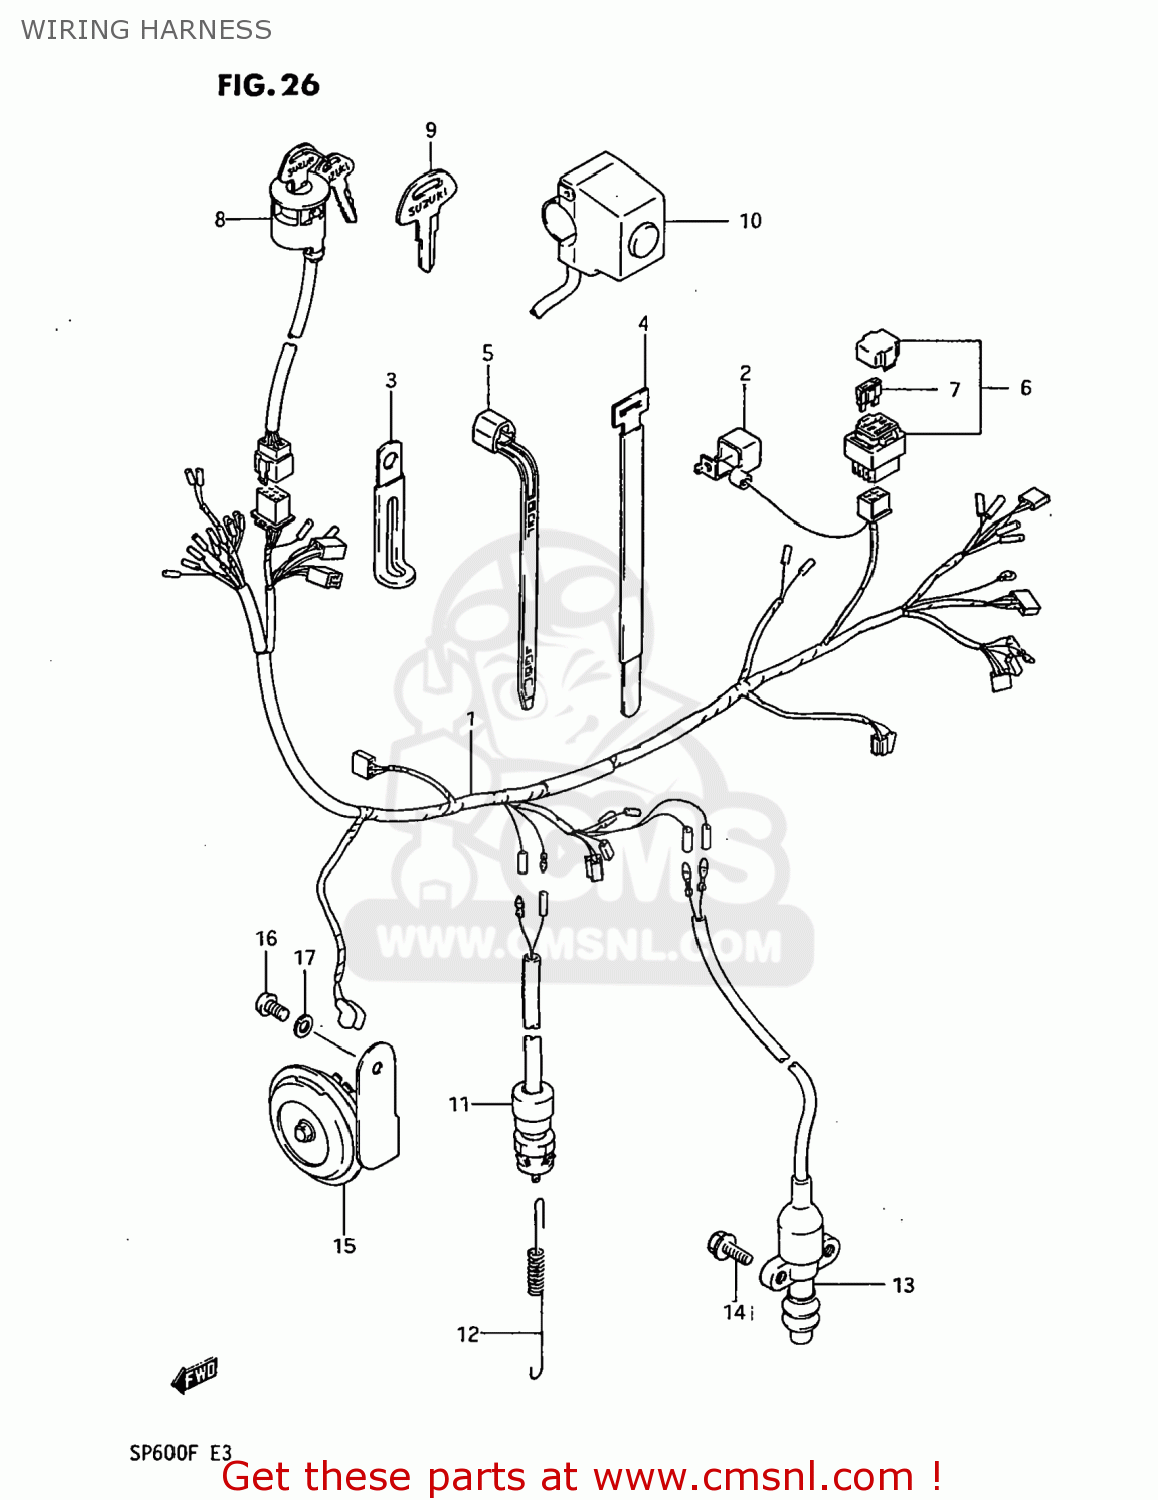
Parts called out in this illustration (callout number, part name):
1	HARNESS,WIRING
2	CAP,BATTERY PLUS TERMINAL
3	CLAMP
4	CLAMP
5	CLAMP(L:95)
6	BOX ASSEMBLY,FUSE
7	FUSE(15A)
8	SWITCH ASSEMBLY,IGNITION
9	KEY,BLANK
10	SWITCH ASSY,ENGINE STOP
11	SWITCH ASSEMBLY,STOP LAMP
12	SPRING
13	SWITCH ASSY,SIDE STAND WARN
14	BOLT
15	HORN ASSY
16	SCREW
17	WASHER,LOCK
